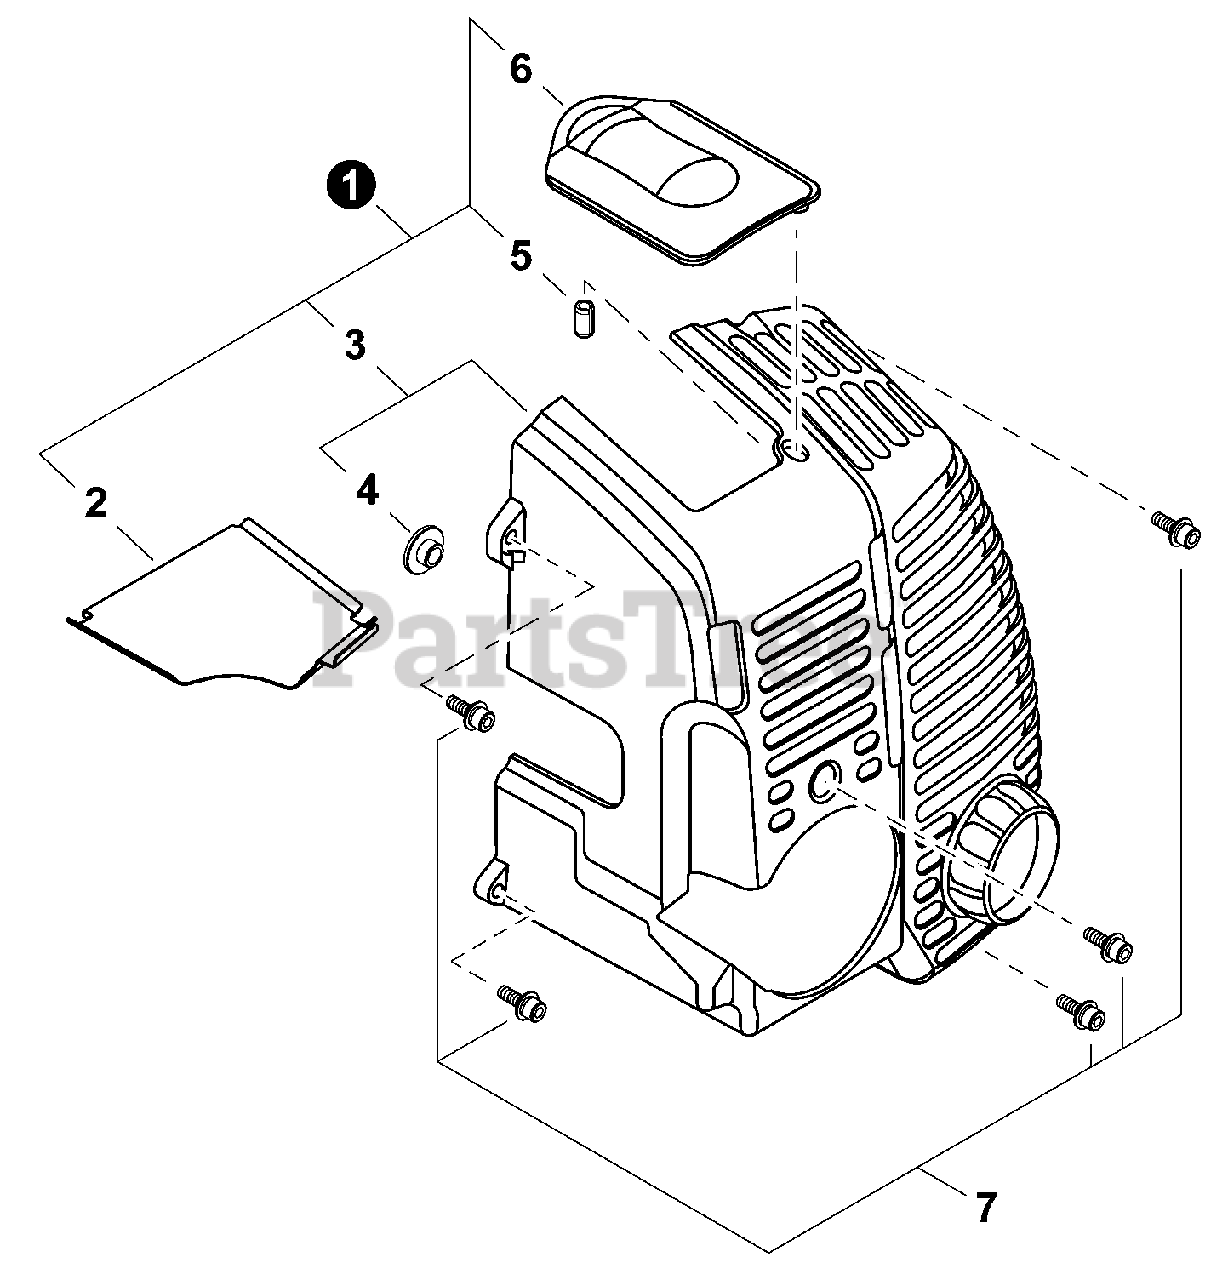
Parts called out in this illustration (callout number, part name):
1	COVER ASSY, ENGINE
2	HEAT SHIELD, EXHAUST
3	COVER, ENGINE
4	COLLAR 5
5	PIN, SPRING 4×8
6	COVER, SPARK PLUG
7	BOLT M5×18
